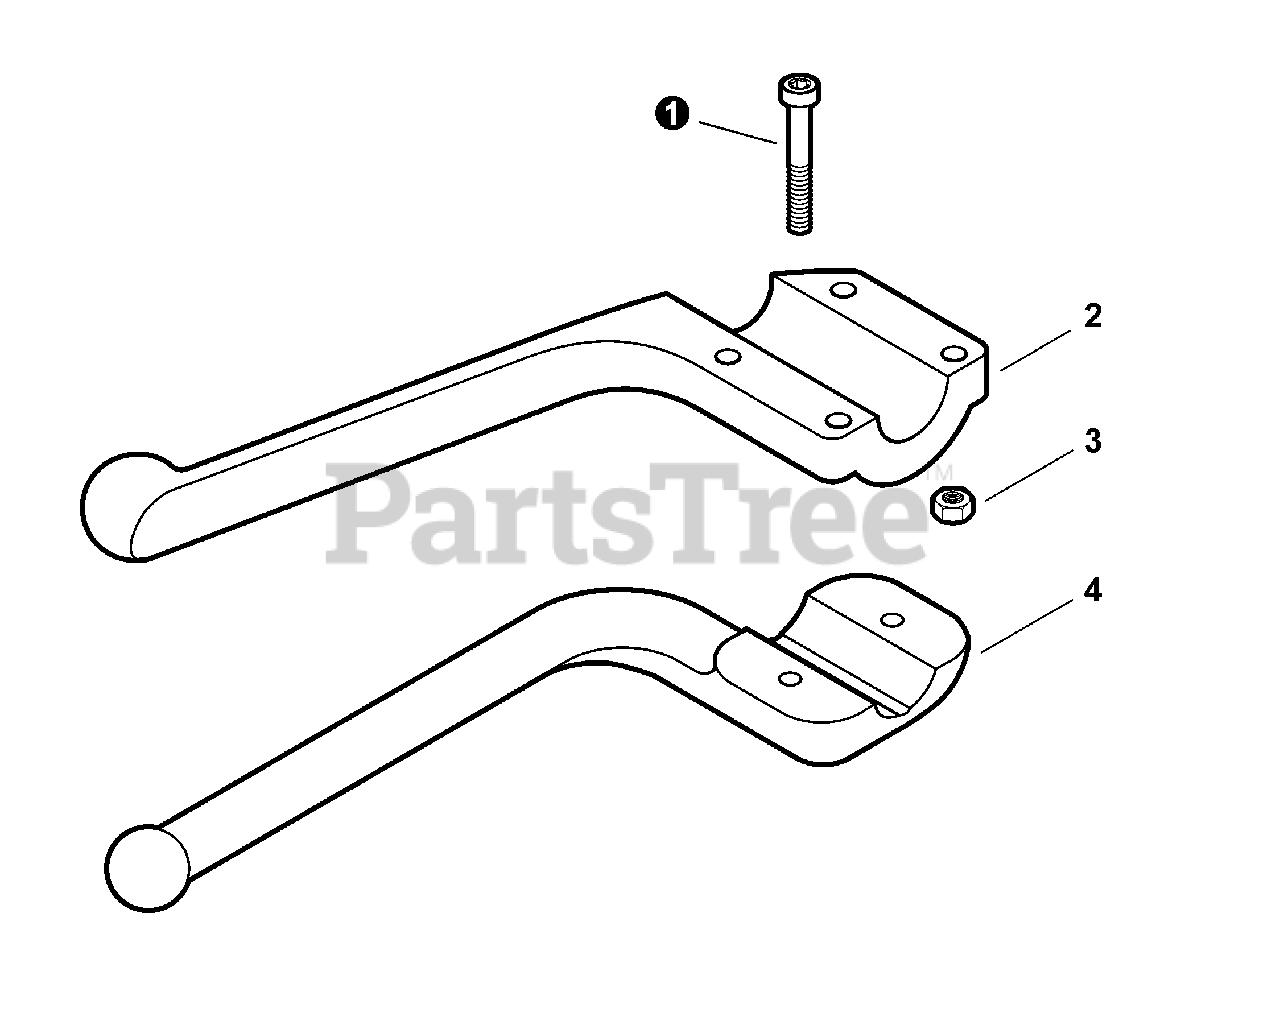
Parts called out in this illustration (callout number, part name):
1	SCREW - 5×35
2	BAR, BARRIER
4	BAR, BARRIER
